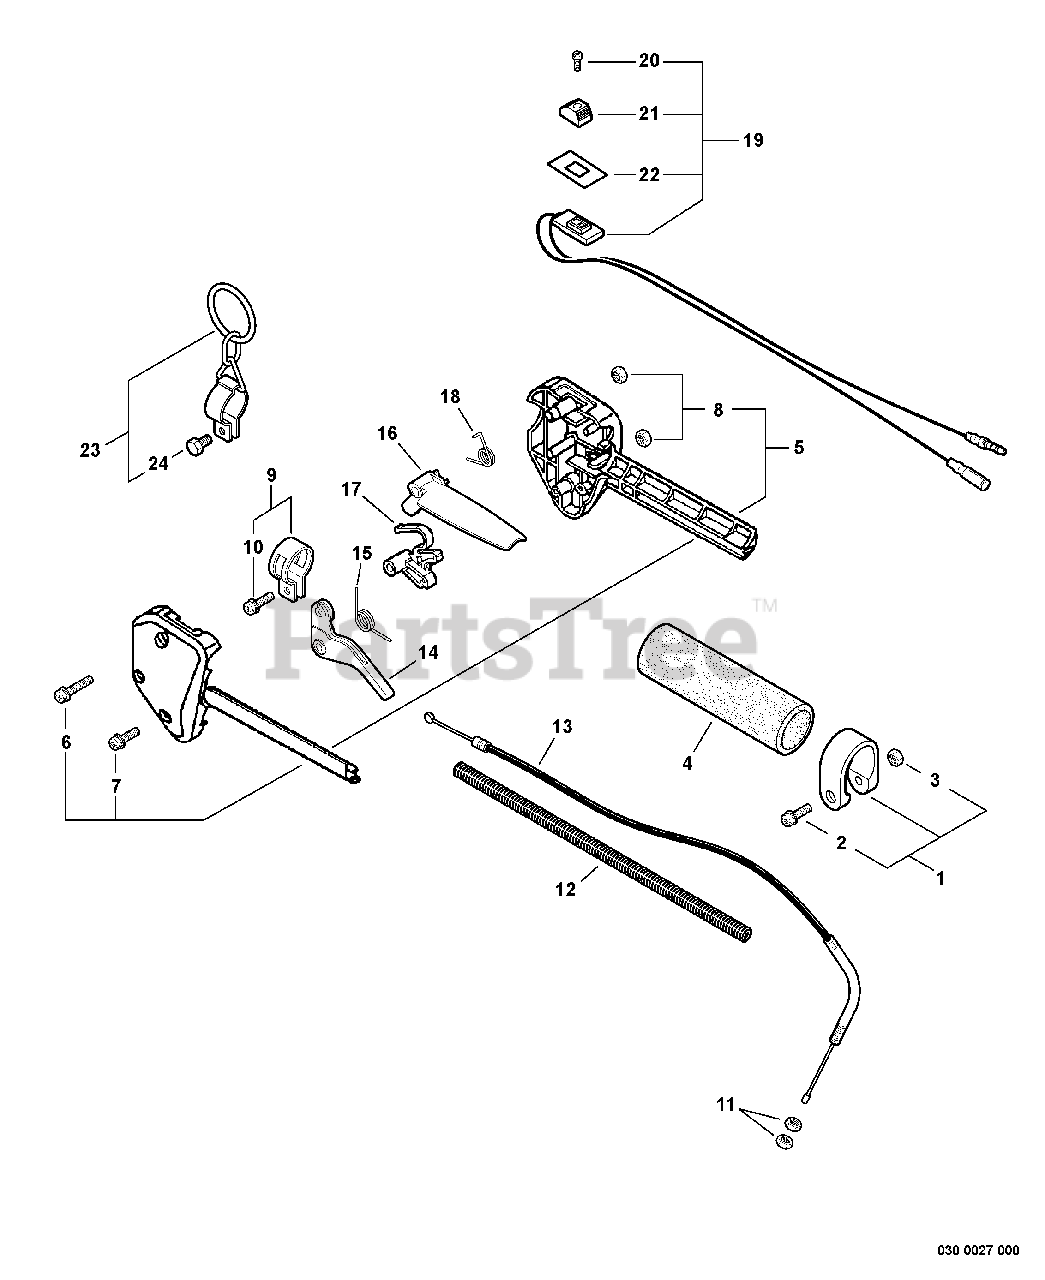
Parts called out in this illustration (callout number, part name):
1	CLAMP KIT
2	SCREW 5×28
3	NUT M5
4	GRIP, HANDLE
5	HANDLE KIT, CONTROL
6	SCREW 5×35
7	SCREW 5×25
8	NUT M5
9	CLAMP KIT
10	SCREW 5×14
12	TUBE, FLEXIBLE
13	CABLE, THROTTLE
14	TRIGGER, THROTTLE
15	SPRING, TORSION
16	LEVER, THROTTLE LOCKOUT
17	LOCKOUT, THROTTLE
18	SPRING, TORSION
19	SWITCH, ON-OFF
20	SCREW 3×10
21	KNOB, SWITCH - ORANGE
22	LABEL, SWITCH
23	HANGER SET, HARNESS
24	BOLT 5×12
